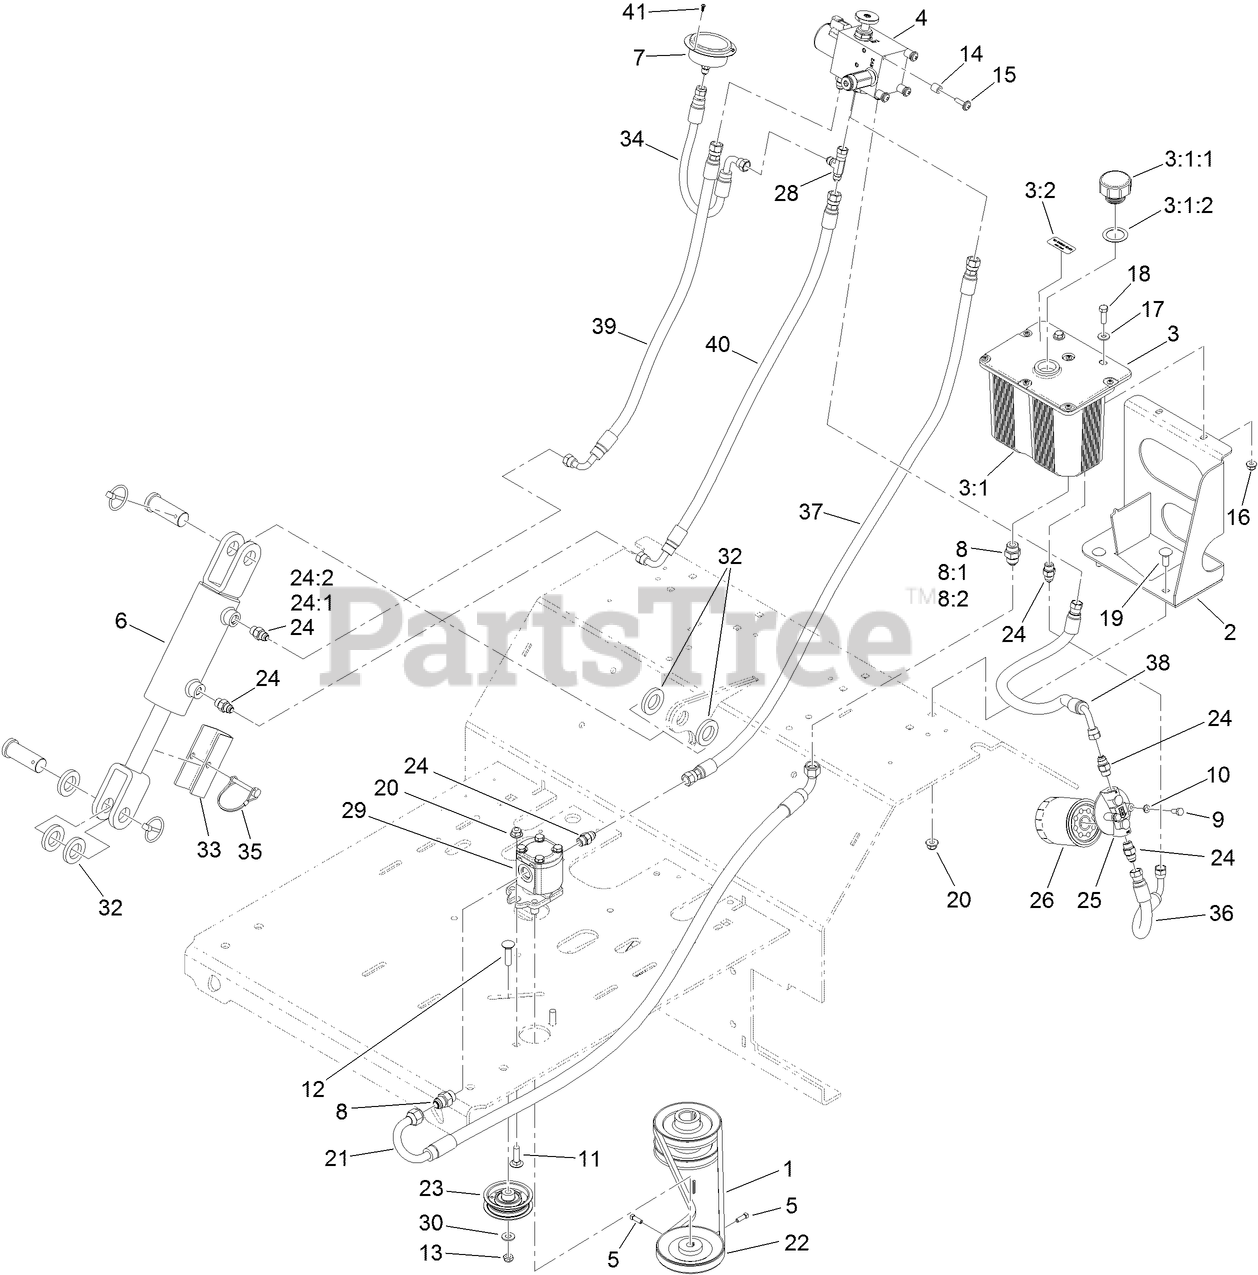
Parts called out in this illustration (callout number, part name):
1	BELT-4L SECTION
2	BRACKET-TANK, HYDRAULIC
3	RESERVOIR ASM
3:1	TANK-HYDRAULIC
3:1:1	CAP-RESERVOIR, HYD
3:1:2	GASKET-CAP
3:2	DECAL-OIL, HYD
4	VALVE-MANIFOLD
5	SCREW-SQH
6	HYD CYLINDER ASM
7	GAUGE-PRESSURE
8	FITTING-STRAIGHT
8:1	O-RING
8:2	O-Ring
9	SCREW-HH
10	WASHER-LOCK
11	BOLT-CARR
12	SCREW-CARR
13	NUT-LOCK, NI
14	SPACER
15	SCREW-PPH
16	NUT-HF, NI
17	WASHER-FLAT
18	SCREW-HH
19	BOLT-CARR
20	NUT-HF, NI
21	HOSE-HYDRAULIC
22	PULLEY
23	PULLEY-IDLER, FLAT
24	FITTING-STRAIGHT
24:1	O-Ring
24:2	O-RING
25	HEAD-FILTER
26	FILTER-OIL, HYD
28	FITTING-HYD, TEE
29	HYDRAULIC PUMP ASM
30	WASHER-FLAT
32	SPACER
33	STOP-CYLINDER
34	HYD HP HOSE ASM
35	PIN-LOCKING
36	HOSE-HYDRAULIC, LP
37	HOSE-HYDRAULIC
38	HOSE-HYDRAULIC
39	HOSE-HYDRAULIC
40	HOSE-HYDRAULIC, HP
41	SCREW-TAP
